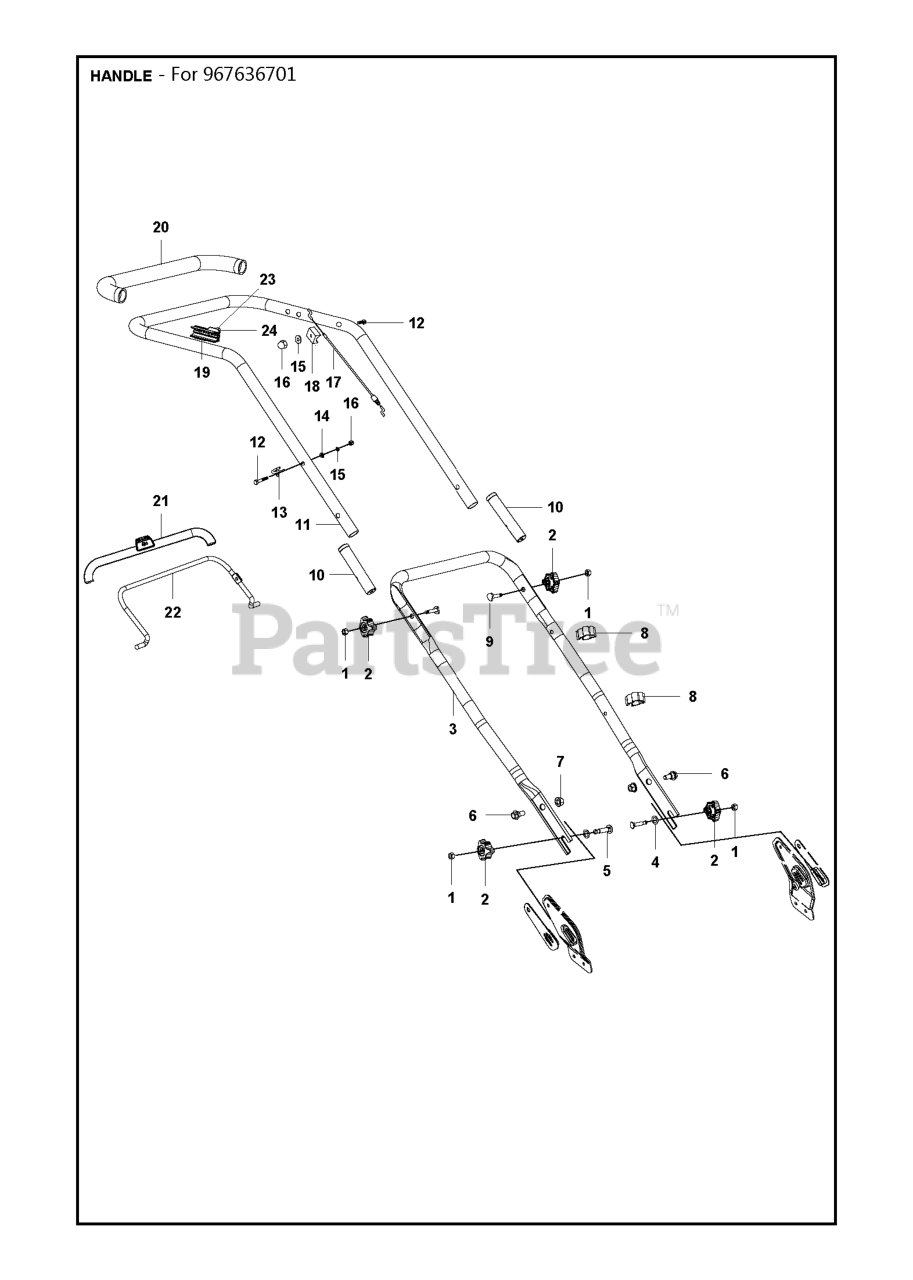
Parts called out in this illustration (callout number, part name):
1	HEXAGON NUT #26800502301
2	KNOB #25341500101
4	SPACER RING
7	LOCKING BOLT M8,GB6187.1 #2680
8	HOLDER CABLE
